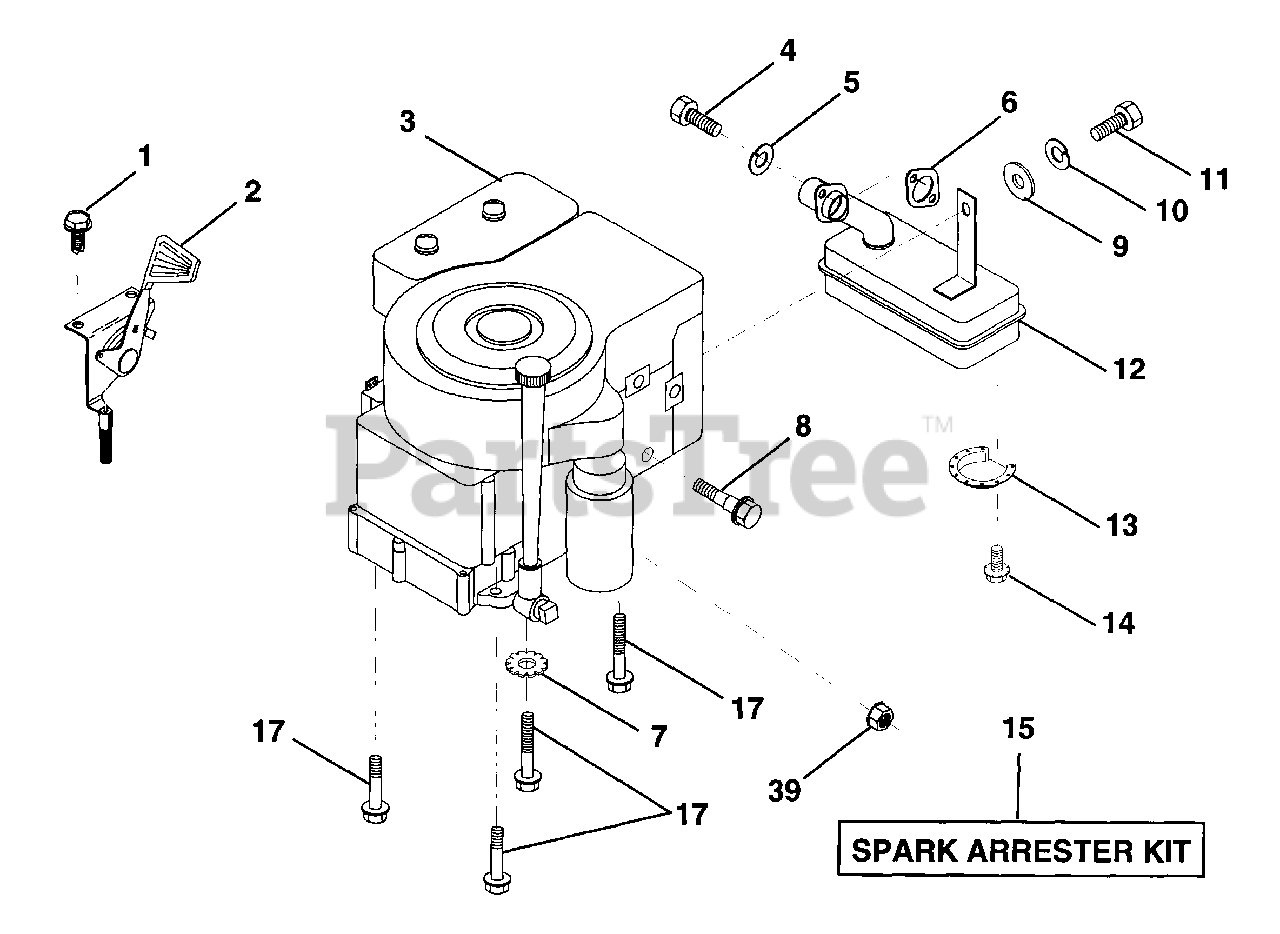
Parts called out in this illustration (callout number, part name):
1	Screw, Hex Thd. Cut 1/4-20 x 1/2
2	Control, Throttle
4	Screw, Hex, Cap 5/16-18 x 3/4
5	Washer, Lock Hvy Hcl Spring 5/16
6	Gasket, Exhaust
7	Washer Lock Ext. Tooth 3/8
8	Bolt, Shoulder 5/16
9	Washer 5/1 6 x 3/4 x 16
10	Washer, Lock Hvy Hlcl Spring 1/4
11	Bolt, Hex Fin.
13	Deflector, Muffler
14	Screw, Spiderlock, Hex Hd 8 x 1/2
15	Arrester, Spark
17	Screw, Hex Washer Head, Thdrol. 3/8-16 x 1-1/2
39	Nut, Flange 1/4-20
